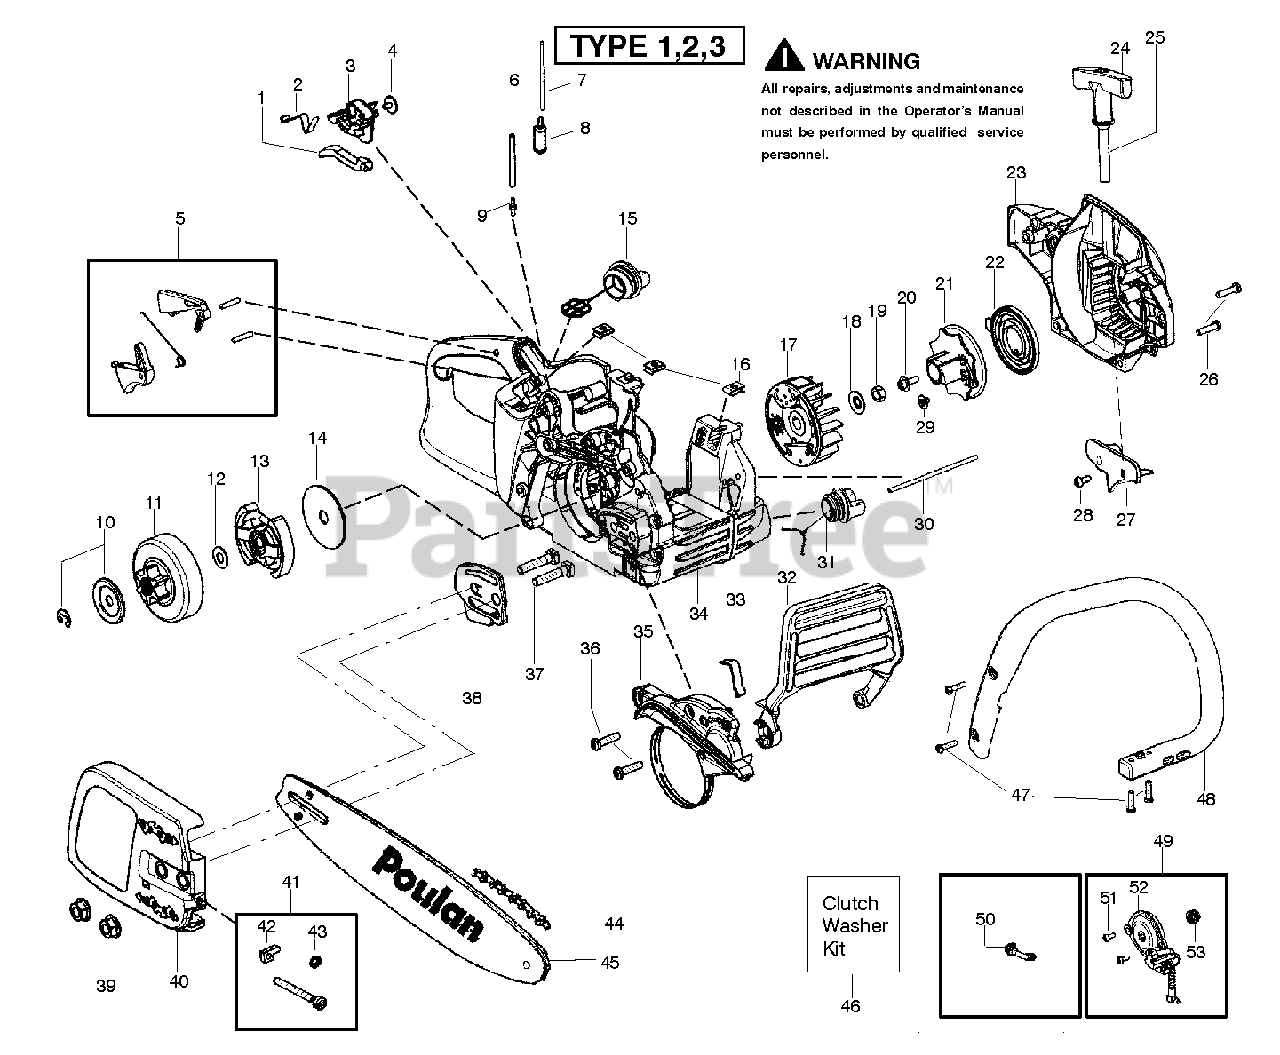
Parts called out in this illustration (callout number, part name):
1	KNOB CHOKE
2	SPRING IGNITION SWITCH
3	LEVER IGNITION SWITCH
5	KIT TRIG AND LOCKOUT
6	LINE KIT
7	KIT-LINE
8	ASSY FUEL PICK UP W/LINE
9	FUEL LINE FITTING
10	KIT SAS CLUTCH WASHER
11	ASSY CLUTCH DRUM 3/8
12	KIT SAS CLUTCH WASHER
13	ASSY CLUTCH
14	WASHER CLUTCH LARGE
15	FUEL CAP ASSY W/RET
18	WASHER-FLYWHEEL
19	NUT-FLYWHEEL
21	STARTER PULLEY
22	SPRING STARTER
23	FAN HOUSING
24	HANDLE STARTER
25	KIT-ROPE
26	SCREW M5.38-14X22.225MM
27	BAFFLE FAN HOUSING
28	SCREW 6-19X.437
30	ASSEMBLY-OIL-VENT
31	OIL TANK CAP
32	HANDGUARD
33	SPRING HANDGUARD
34	ASSEMBLY
35	KIT CHAIN BRAKE
36	SCREW M5.38-14X22.225MM
38	PLATE BAR MOUNTING
40	ASSY CLUTCH COVER PLN GREEN
41	RETAINER
42	ADJUST PIN,BAR 36/41
43	RETAINER
44	CHAIN 18" 91VJ 62DL 3/8 .050
46	KIT SAS CLUTCH WASHER
47	SCREW M5.38-14X22.225MM
48	HANDLE FRONT
49	KIT OIL PUMP
50	ASSY PICK UP OIL TANK
52	ASSY OIL PUMP
53	WORM GEAR
